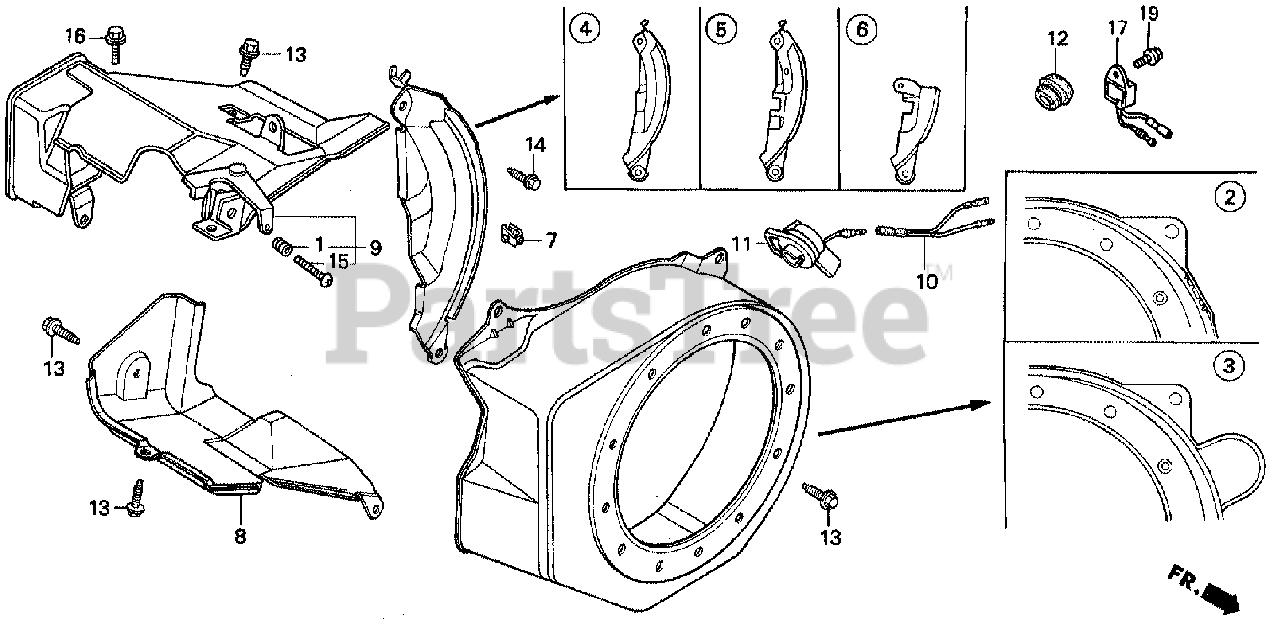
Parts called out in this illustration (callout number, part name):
2	COVER, FAN *R8* (BRIGHT RED)
2	COVER, FAN *NH1* (BLACK)
4	PLATE, SIDE (OIL ALERT)
4	PLATE, SIDE (STD)
4	PLATE, SIDE
7	CLAMP, CORD
7	CLIP, HARNESS
8	SHROUD
10	SUB-HARNESS
11	SWITCH ASSY., ENGINE STOP
13	BOLT, FLANGE (6X12) (CT200)
14	BOLT, FLANGE (6X20) (CT200)
17	ALERT UNIT, OIL
19	BOLT, FLANGE (6X8)
